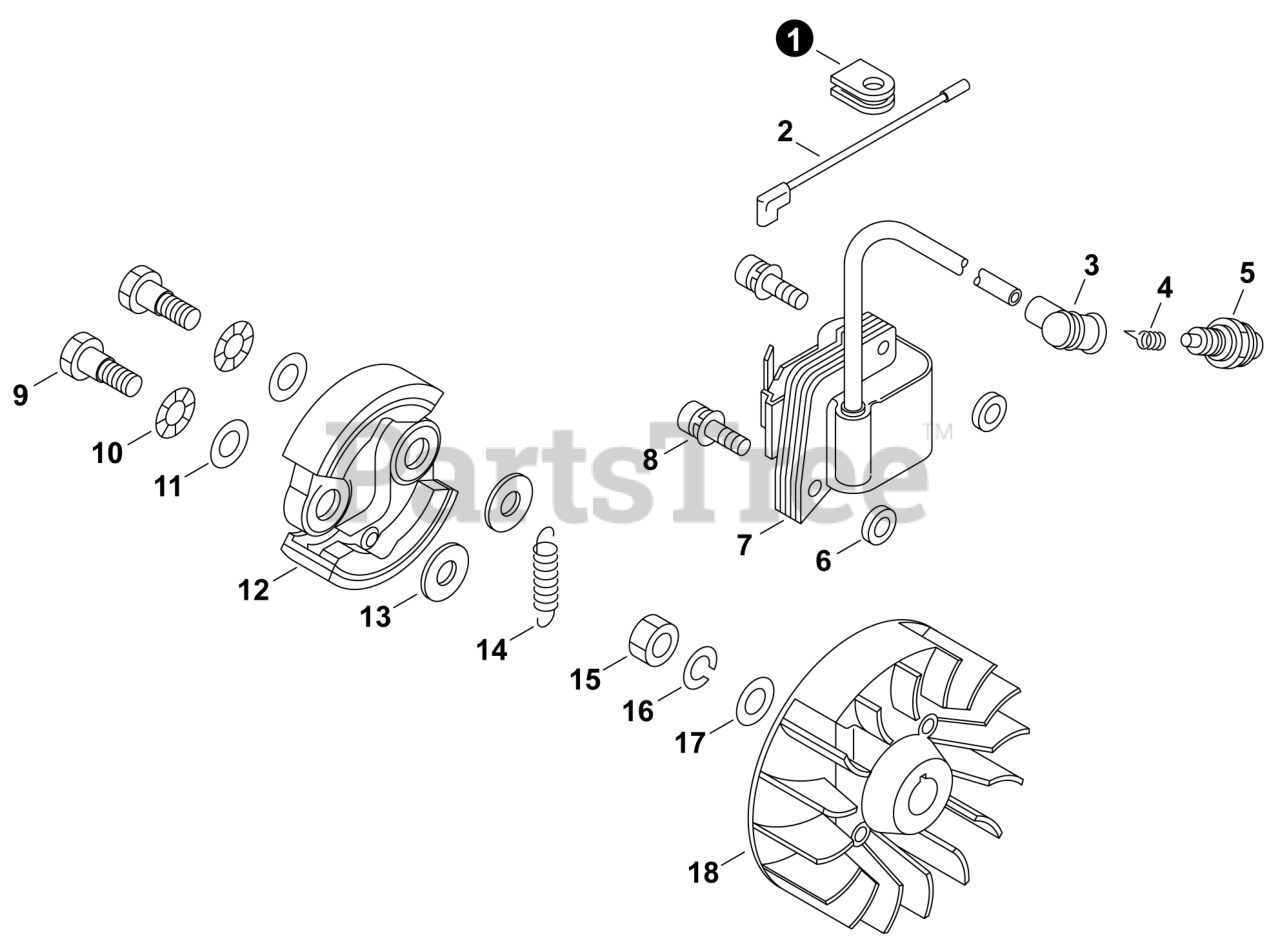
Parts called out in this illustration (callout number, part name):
2	LEAD 315L
3	CAP, SPARK PLUG
4	TERMINAL, SPARK PLUG
5	SPARK PLUG - BPM7Y
7	COIL, IGNITION
8	BOLT 4x22
9	BOLT, CLUTCH 8x7.9xM6
10	WASHER, SPRING 8.5x16x0.5
11	WASHER 8
12	SHOE, CLUTCH
13	WASHER 6
14	SPRING, TENSION
15	NUT 8x1.25
16	WASHER, SPRING 8
17	WASHER 8.5x16x1.2
18	FLYWHEEL
